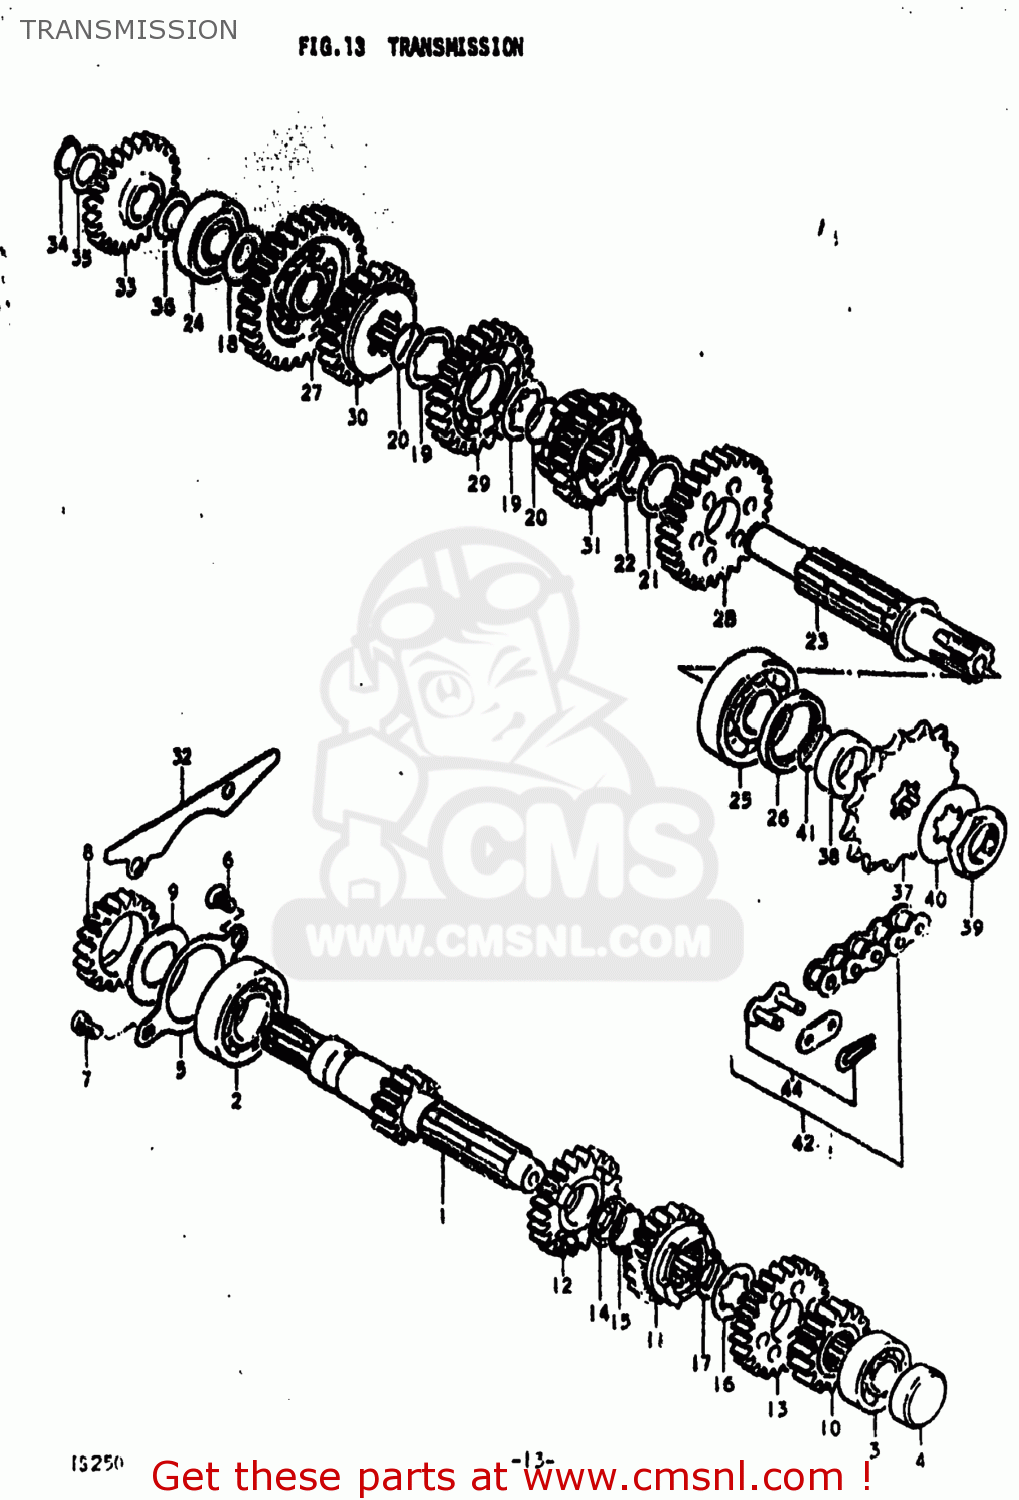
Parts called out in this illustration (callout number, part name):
1	SHAFT,COUNTER
2	BEARING
3	BEARING
4	PLUG
5	PLATE,COUNTERSHAFT BEARING
6	SCREW
7	SCREW
8	GEAR,KICK STARTER DRIVE
9	WASHER(25X41X3)
10	GEAR,SECOND DRIVE
11	GEAR,THIRD DRIVE
12	GEAR,FOURTH DRIVE
13	GEAR,FIFTH DRIVE
14	SHIM
15	CIRCLIP
16	WASHER,LOCK
17	CIRCLIP
18	WASHER
19	WASHER
20	RING,SNAP
21	WASHER
22	RING,SNAP
23	SHAFT,DRIVE
24	BEARING
25	BEARING
26	SEAL,OIL(32X42X6)
27	GEAR,FIRST DRIVEN
28	GEAR,SECOND DRIVEN
29	GEAR,THIRD DRIVEN
30	GEAR,FOURTH DRIVEN
31	GEAR,5TH DRIVEN
32	PLATE,OIL RESERVOIR
33	GEAR,KICK STARTER IDLE
34	CIRCLIP
35	WASHER
36	WASHER
37	SPROCKET,ENGINE
38	SPACER(22X32X11.5)
39	NUT
40	WASHER,LOCK
41	O RING(D:1.7,ID:22)
42	CHAIN,DRIVE #525TR-10
43	JOINT ASSEMBLY,CHAIN
